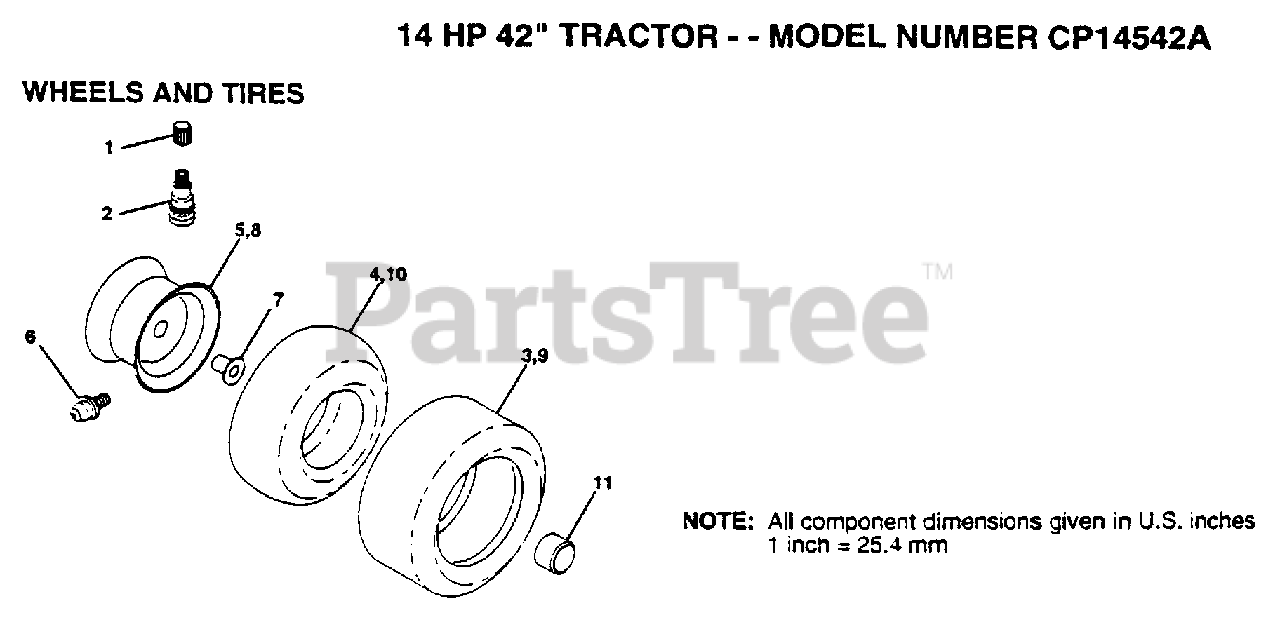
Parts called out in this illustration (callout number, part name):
1	VALVE CAP
2	VALVE STEM LT
4	TUBE.5.3/4.5/6
5	"RIM,FRT T"
6	FITTING LT
7	"FLANGE, BEARING"
8	"RIM 8"""
9	TIRE.20X8-8
10	TUBE.18X9.5-8
11	HUB CAP
